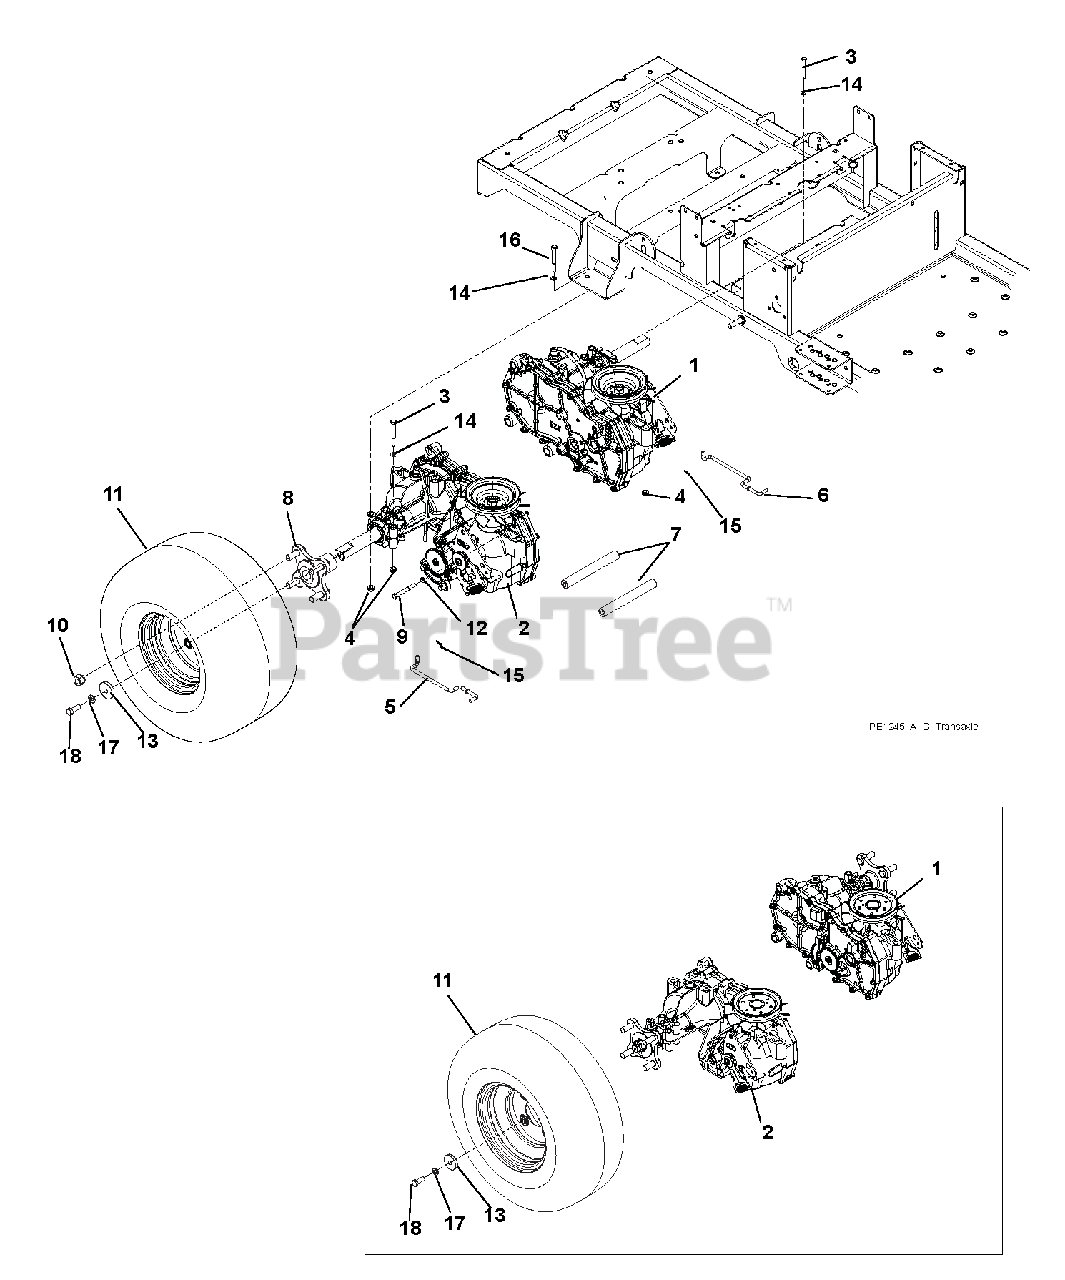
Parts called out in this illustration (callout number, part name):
1	TRANSAXLE, LH EZT D-SHAFT
2	TRANSAXLE, RH EZT D-SHAFT
3	@BLT-HEX .31-18X2.25 GR5 YWZC
4	@NUT-LK-NYL-FLG .31-18 YWZC
5	DUMPVALVE, RH LCZ
6	DUMPVALVE, LH LCZ
7	SHAFT, CROSS BRACE
8	ASM, WHEEL HUB
9	@BLT-HEX .38-16X2.50 GR5 YWZC
10	WHEEL NUT .500-20 YZ
11	TIRE-ASM 18X6.5-8 4 PLY DSHAFT
11	TIRE/WHEEL ASSY, 18X8.50-8 CTR
11	TIRE/WHEEL ASSY, 18X9.50-8 OFF
12	WSHR-FL-STL .406X1.00X.188 YWZ
13	WSHR,FLT STL.406X1.50X.245YWZC
14	@WSHR-FL-STL.38X.875X.083 YWZC
15	PIN-HAIR INT .06X.18X.77
16	@BLT-HEX .31-18X2.75 GR5 YWZC
17	@WSHR-LK .38X.094 REG YWZC
18	@BLT-HEX .38-16X1.00 GR5 YWZC
